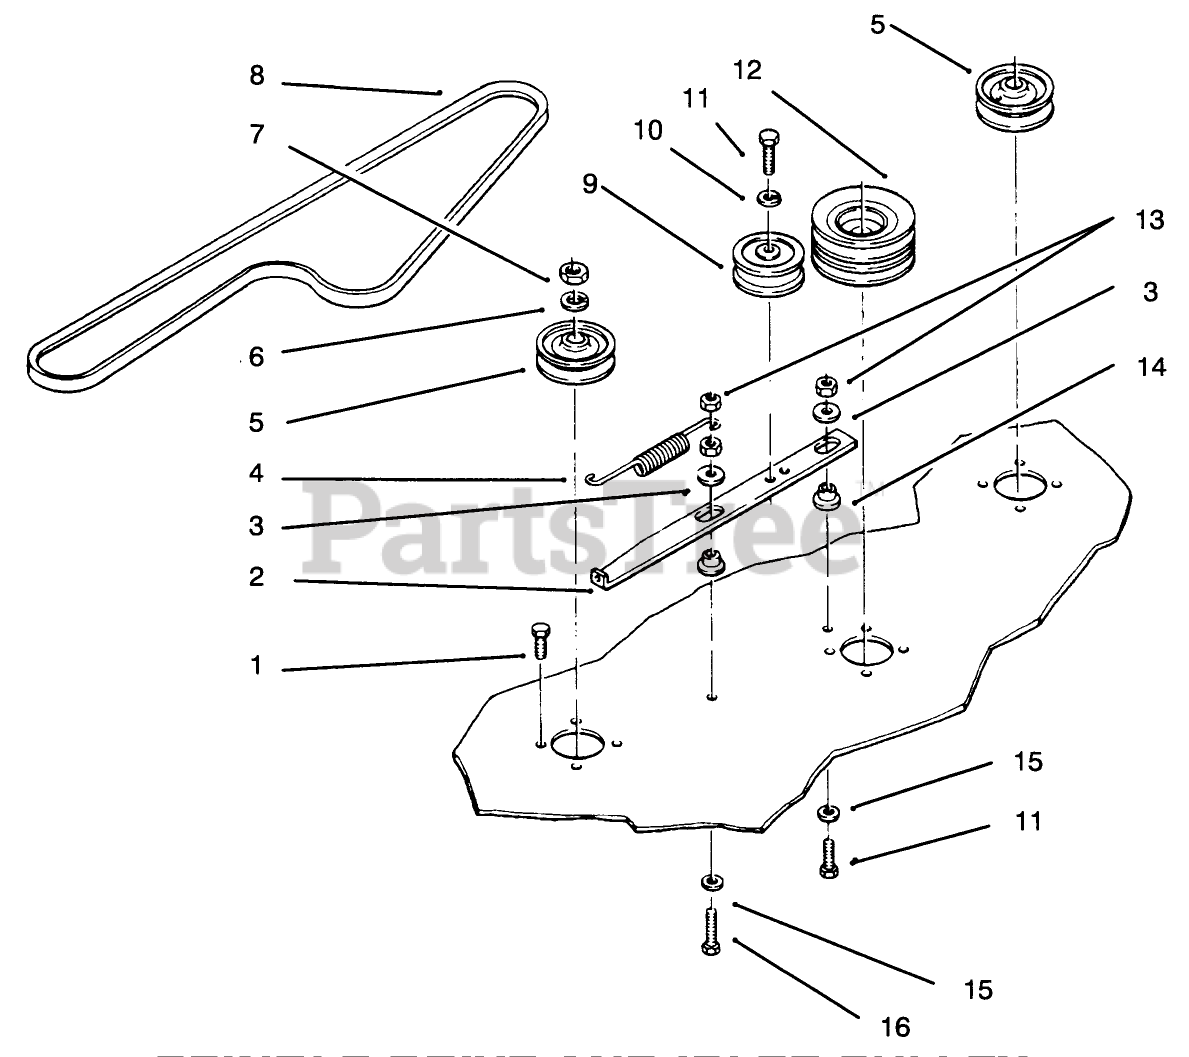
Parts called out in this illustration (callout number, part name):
1	SCREW-HH
2	BAR-IDLER SUPPORT
3	WASHER
4	SPRING-EXTENSION
5	PULLEY
6	WASHER-LOCK
7	NUT-JAM
8	V-BELT
9	PULLEY-IDLER
10	WASHER-LOCK
11	SCREW-HH
12	PULLEY CENTER
13	NUT-LOCK, NI
14	SPACER-BUSHING
15	WASHER
16	SCREW-HH
